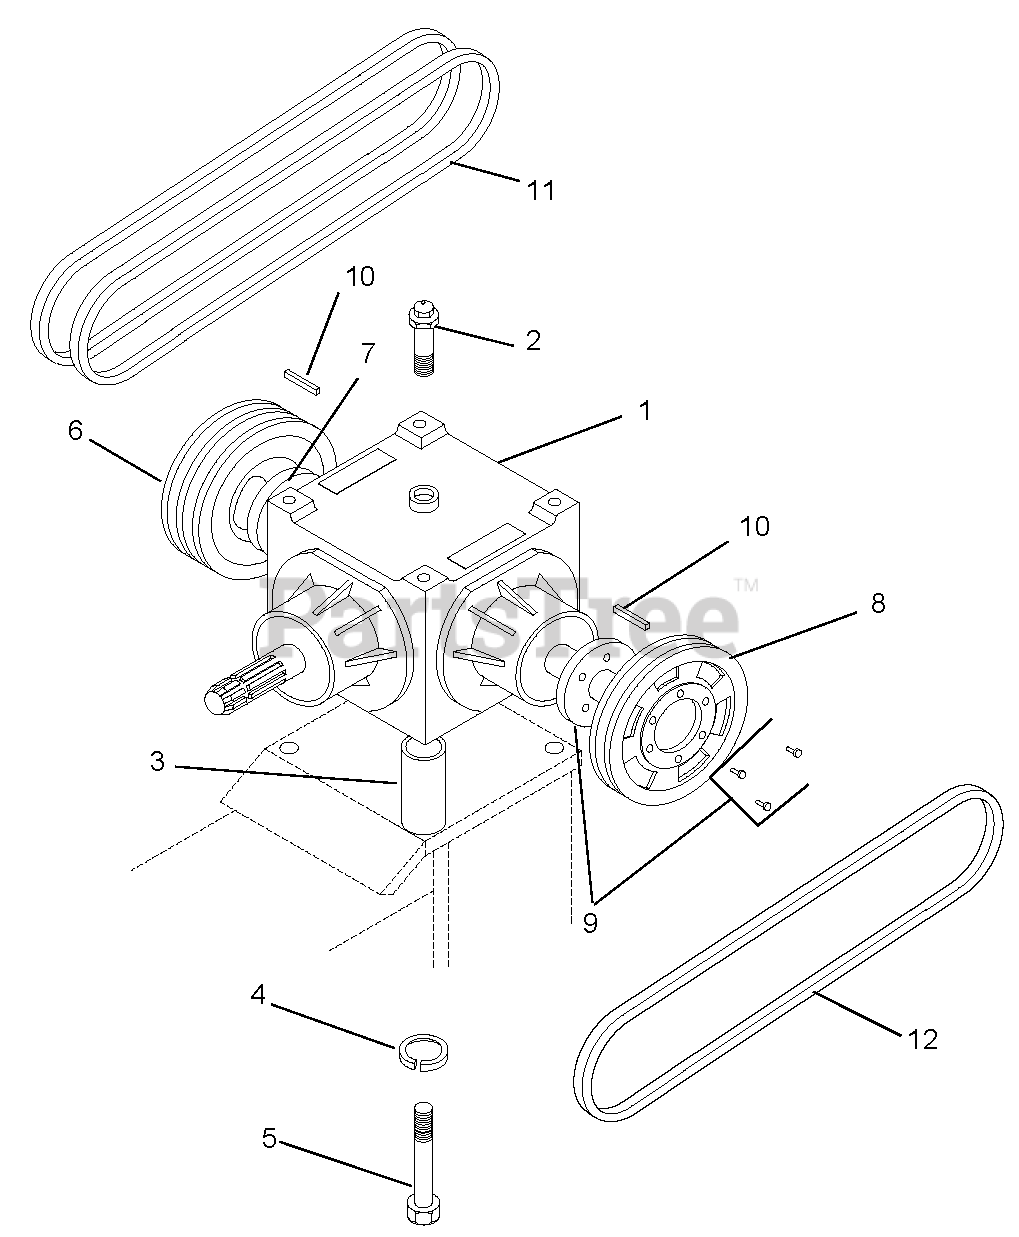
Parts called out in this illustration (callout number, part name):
1	Gearbox Assembly
2	Plug, Oil Level
3	Spacer, Gearbox Mounting
4	Washer, Lock .50
5	Cap Screw, Hex Head .50-13 x 3
6	Pulley, 2-Belt
7	Bushing 1.125 (SK)
8	Pulley, 1-Belt
9	Bushing 1.125 (SDS)
10	Key .25 x .25 x 2.00
11	V-Belt, B78
12	V-Belt, B70
